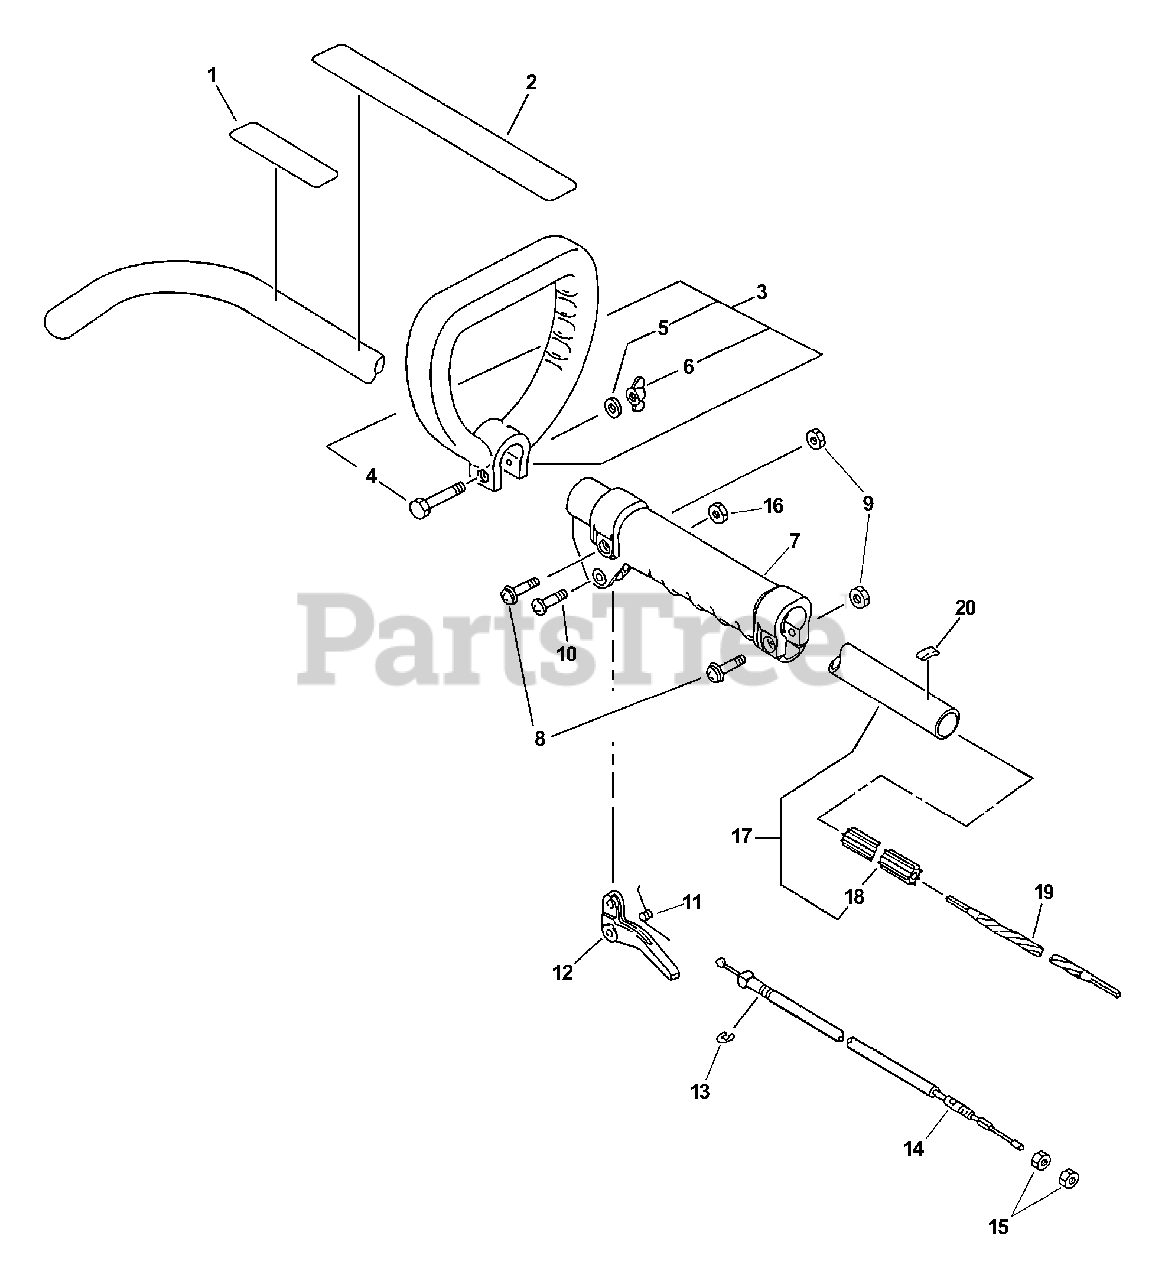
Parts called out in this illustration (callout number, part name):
1	LABEL, CAUTION
2	LABEL, CAUTION
2	LABEL - CAUTION
3	HANDLE ASSY
4	BOLT 1/4"-20×1-1/2"
5	WASHER, 1/4"
6	NUT, WING 1/4"-20
8	SCREW 5×25
9	NUT M5
11	SPRING, THROTTLE
12	TRIGGER, THROTTLE
13	RING, RETAINING - 5
14	CABLE, THROTTLE
16	NUT, LOCK M5
17	MAIN PIPE ASSY
18	LINER - FLEXIBLE
19	DRIVESHAFT - FLEXIBLE
20	LABEL - ALIGNMENT
